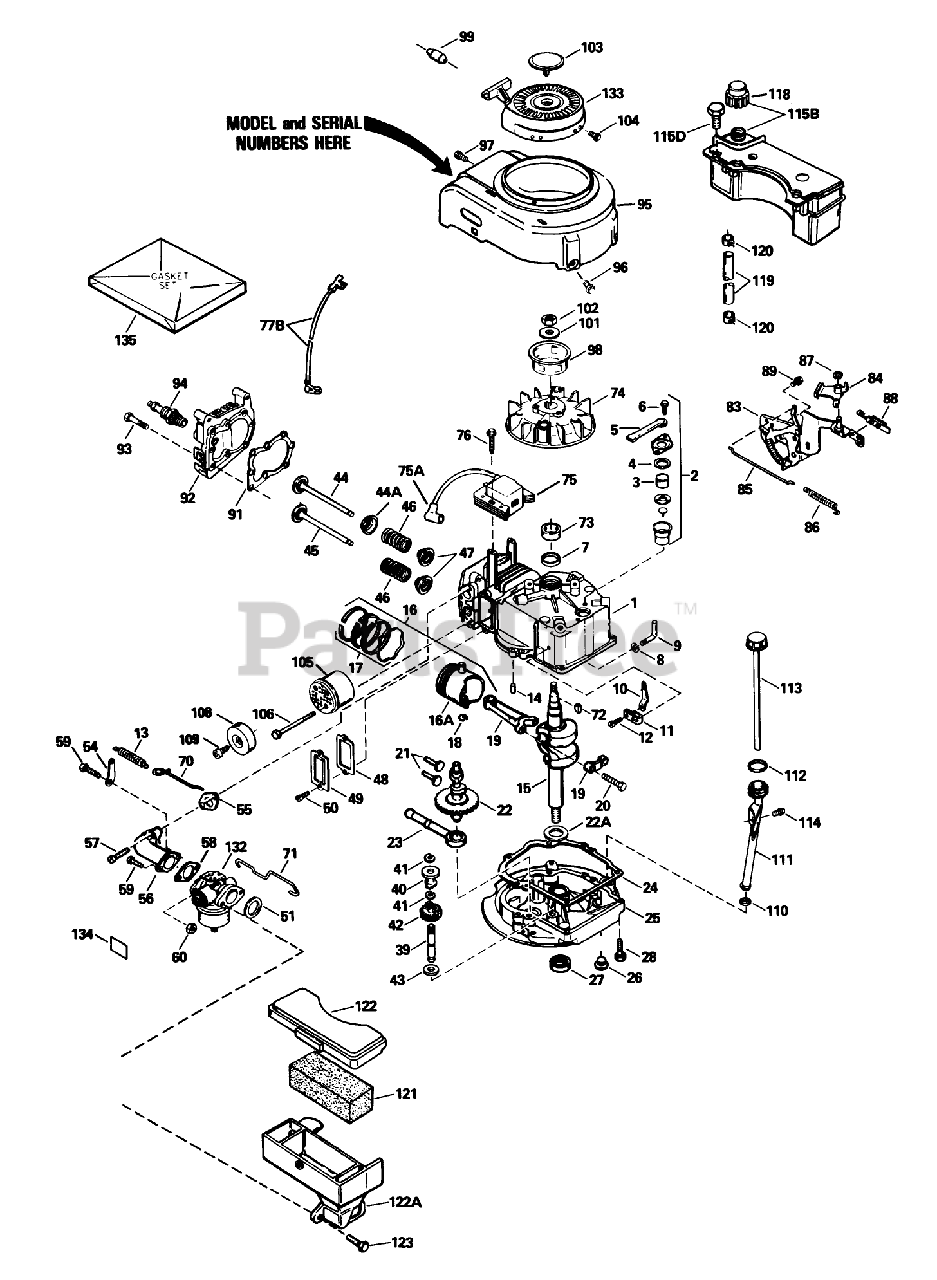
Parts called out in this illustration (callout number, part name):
1	Cylinder Assembly (Incl. Ref. #2, 4, 94 96)
2	Breather Assy. (Incl. Ref. #46 thru 51)
3	Element-Breather
4	Gasket-Breather
5	Tube, Breaker
6	Screw (10-24 x 9/16)
7	Seal-Oil
8	Washer-Flat
9	Rod, Governor (Incl. No. 36)
10	Governor Lever
11	Clamp-Lever, Governor
12	Screw
13	Spring Governor
14	Pin-Dowel
15	Crankshaft
16	Piston-Pin Ring Assy. (Std.)(Incl. Ref. #14A, 15 16)
16	Piston-Pin Ring Assy. (.010 oversize)(Incl. Ref. #14A, 15 16)
16	Piston-Pin Ring Assy. (.020 oversize)(Incl. Ref. #14A, 15 16)
16A	Piston Pin Assy. (Std)(Incl. Ref. #16)
16A	Piston Pin Assembly (.010 oversize) (Incl. Ref. #18)
16A	Piston Pin Assembly (.020 oversize) (Incl. Ref. #18)
17	Piston Ring Set Std.
17	Piston Ring Set .010 O.S.
17	Piston Ring Set .020 O.S.
18	Ring-Retaining, Piston Pin
19	Rod Assy., Connecting (Incl. Ref. #17)
20	Bolt-Rod, Connecting
21	Lifter-Valve
22	Camshaft(Mech.Comp. Release)
22A	Washer-Thrust
23	Oil Pump ASM
24	Gasket
25	Flange-Mounting (Incl. Ref. #26, 27 39)
26	Plug Oil Drain
27	Seal-Oil
28	Screw (1/4-20 x 1-1/4)
39	Shaft-Governor
40	Spool-Governor
41	Ring-Retaining
42	Governor Gear ASM
43	Washer
44	Valve, Intake (Std.) (Incl. Ref. #40)
44	Valve, Intake (1/32" oversize)(Incl. No. 40)
44A	Seal Assy., Intake
45	Valve, Exhaust (Std.)(Incl. No. 40)
45	Valve, Intake (1/32" oversize)(Incl. No. 40)
46	Spring-Valve
47	Cap-Valve, Spring
48	Gasket-Cover, Valve
49	Cover-Valve
50	Screw
51	Gasket-Cleaner, Air
54	Lever-Adjusting, R P M
55	Gasket-Intake Pipe
56	Pipe-Intake (Incl. Ref. #59)
57	Screw (1/4-20 x 1)
58	Gasket
60	Nut and Lock Washer (1/4-28)
70	Link-Governor
71	Link-Throttle
72	Key-Flywheel
73	Spacer
74	Flywheel
75	Solid State
75A	Cover-Spark Plug
76	Screw
77B	Ground Wire
83	Bracket-S.E. Brake
84	Lever-Brake
85	Link-Control
86	Spring-Extension
87	Ring-Retaining
88	Terminal
89	Screw (1/4-20 x 3/8)
91	Gasket-Cylinder Head
92	2025A67 ADD.ASSEMBL
93	Screw (5/16-18x1-1/2)
94	Spark Plug-Resistor (R J19 L M)
95	Housing-Blower
96	Screw (1/4-20 x 1/2)
97	Screw (10-24 x 9/16)
98	Hub-Starter
99	Retainer-Starter Rope
101	Washer-Belleville
102	Nut-Flywheel
103	Plug Starter
104	Screw, Hex Hd.
105	Muffler Assembly (Incl. Ref. #106)
106	Screw
108	Cover-Muffler
109	Screw (8-32 x 3/8)
110	Gasket
111	Oil Fill Tube
112	O-Ring
113	Dipstick
114	Screw (10-32 x 1/2)
115B	Tank Assembly-Fuel (Incl. Ref. #102)
115D	Screw (10-32 x 35/64)
118	Cap-Fuel
119	Line-Fuel
120	Clamp-Line, Fuel
121	Filter-Air Cleaner
122	Cover-Air Cleaner
122A	Body Air cleaner
123	Screw
132	Carburetor (Incl. Ref. #83)
133	Starter-Rewind
134	Decal-Primer
135	Gasket Set (Incl. Items Marked *)
